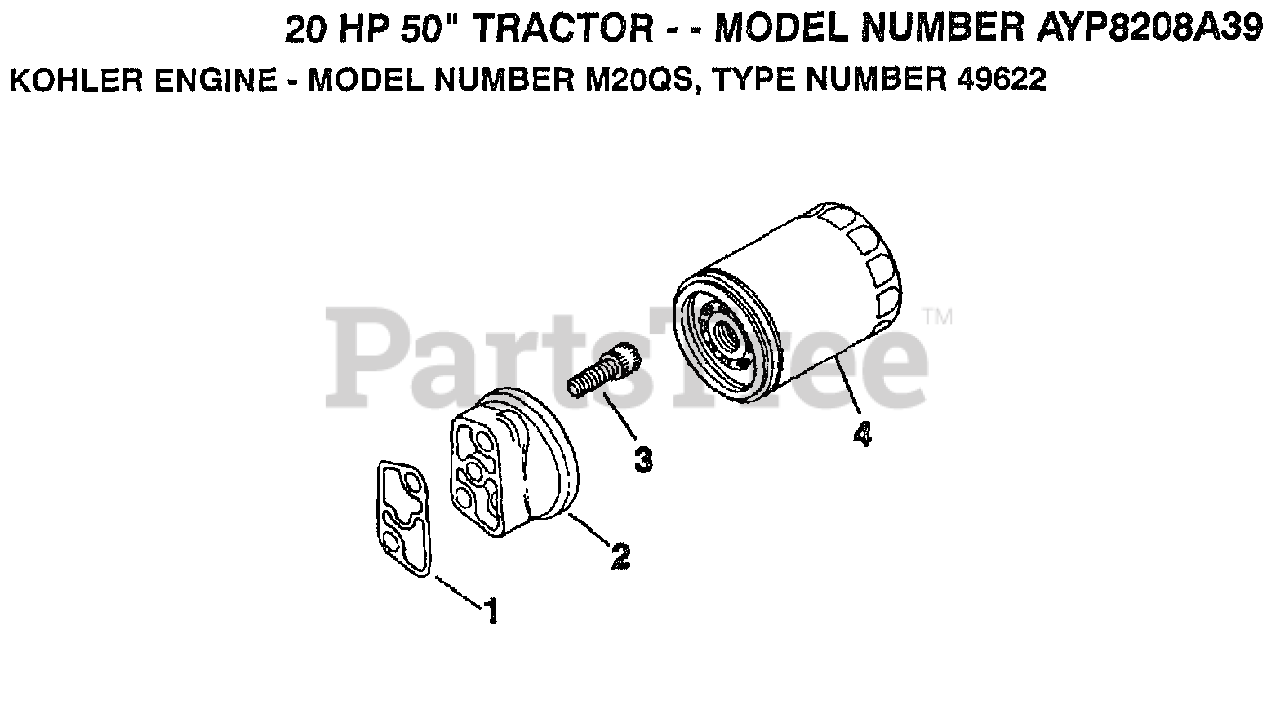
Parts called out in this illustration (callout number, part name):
1	GASKET, OIL FILTER
2	ADAPTER, OIL FILTER
3	SCREW
